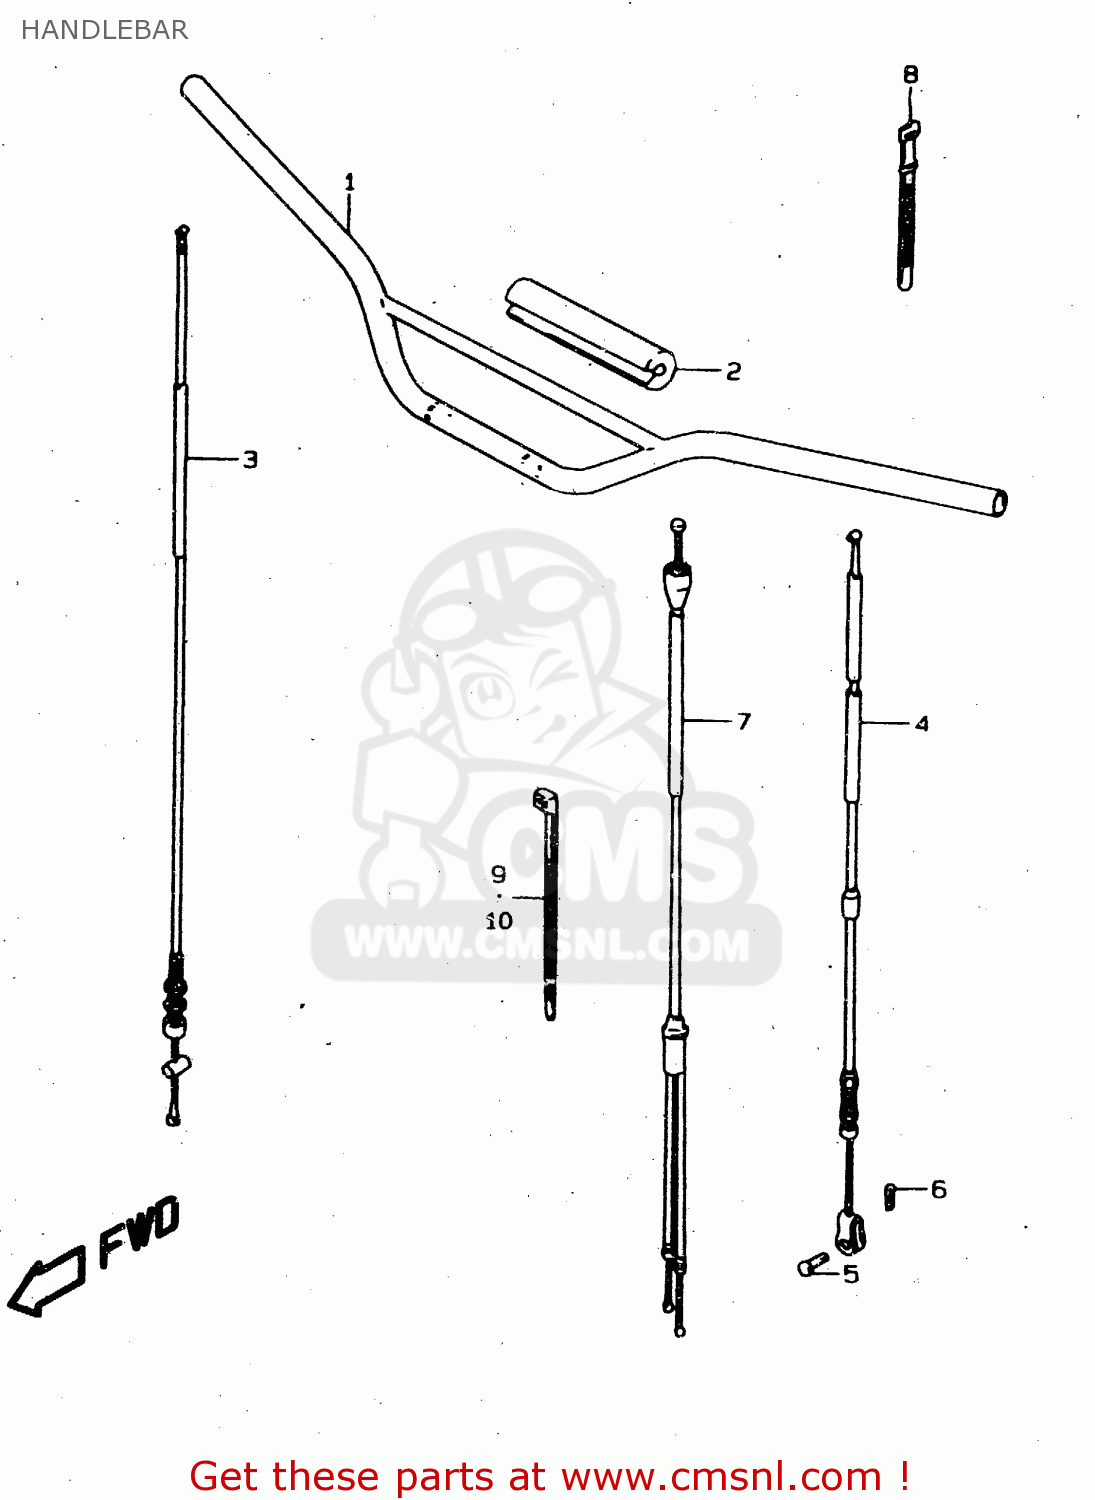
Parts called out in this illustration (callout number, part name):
1	HANDLEBAR
2	PAD,CROSSBAR
3	CABLE,FR BRAKE
4	CABLE ASSY,CLUTCH
5	PIN(L:13)
6	PIN
7	CABLE ASSEMBLY,THROTTLE
8	CLAMP(L:145)
9	CLAMP(L:125)
10	CLAMP(L:165)
